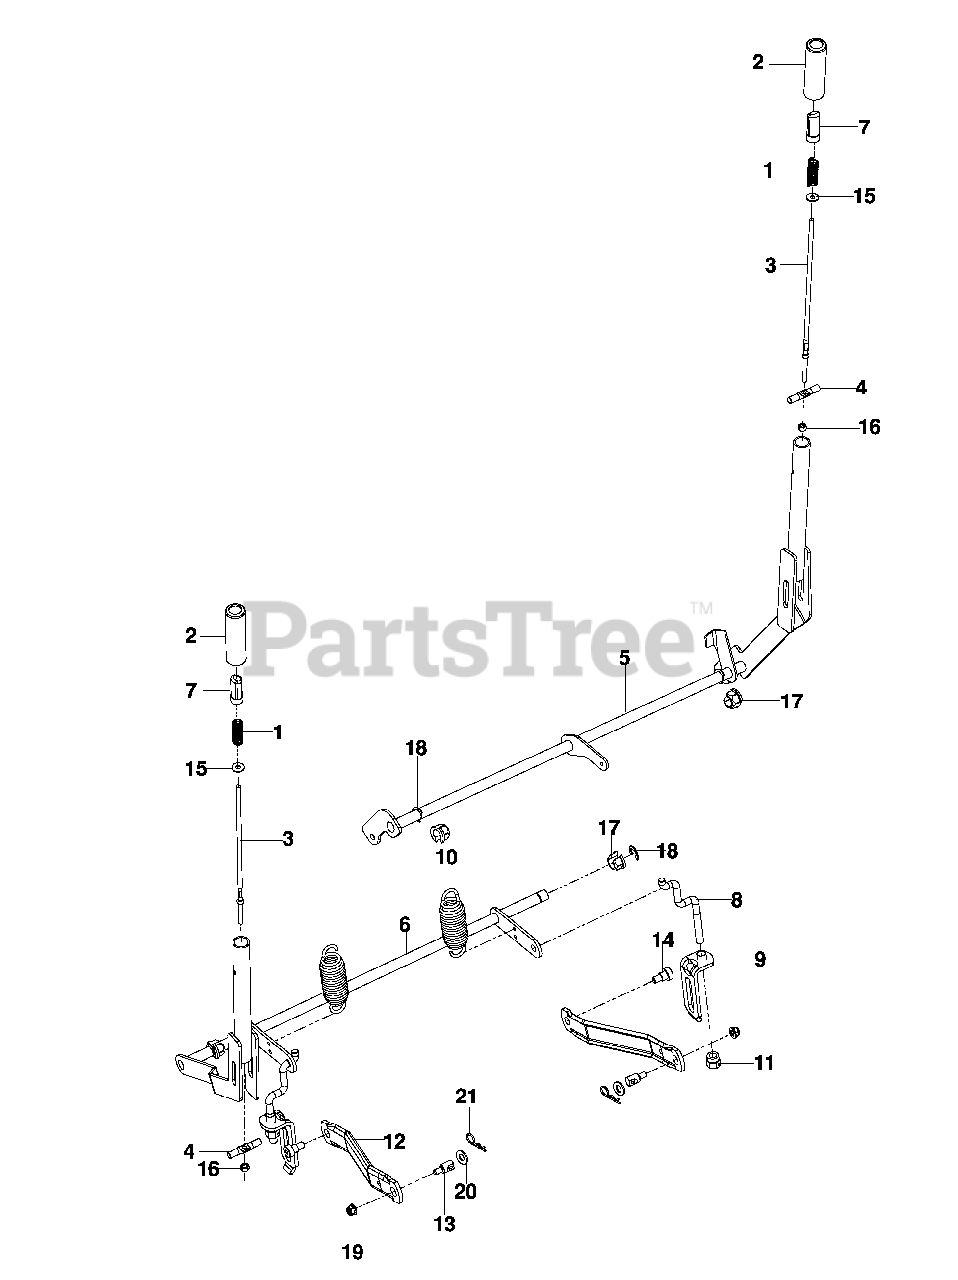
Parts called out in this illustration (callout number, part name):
1	SPRING, COMPRESSION
2	GRIP, HANDLE
3	ROD, HANDLE RELEASE
4	ROD, LATCH RELEASE
5	SHAFT, BRAKE
6	SHAFT, LIFT
7	BUTTON, PUSH
8	LINK, REAR SUSPENSION
9	BRACKET, CENTERING LNK
11	NUT, LIFT LINK
12	ARM, SUSPENSION RR
13	STUD, w/ANTI- ROTATE
14	BOLT 3/8-16 x 3/8 SKT HD
15	WASHER ¼ FLAT
16	NUT ¼-20 HEX NYLOC
17	PLASTIC NUT
19	NUT 5/16-18 FLANGE NYLOC
20	WASHER 5/8, SAE
21	HAIRPIN #4
